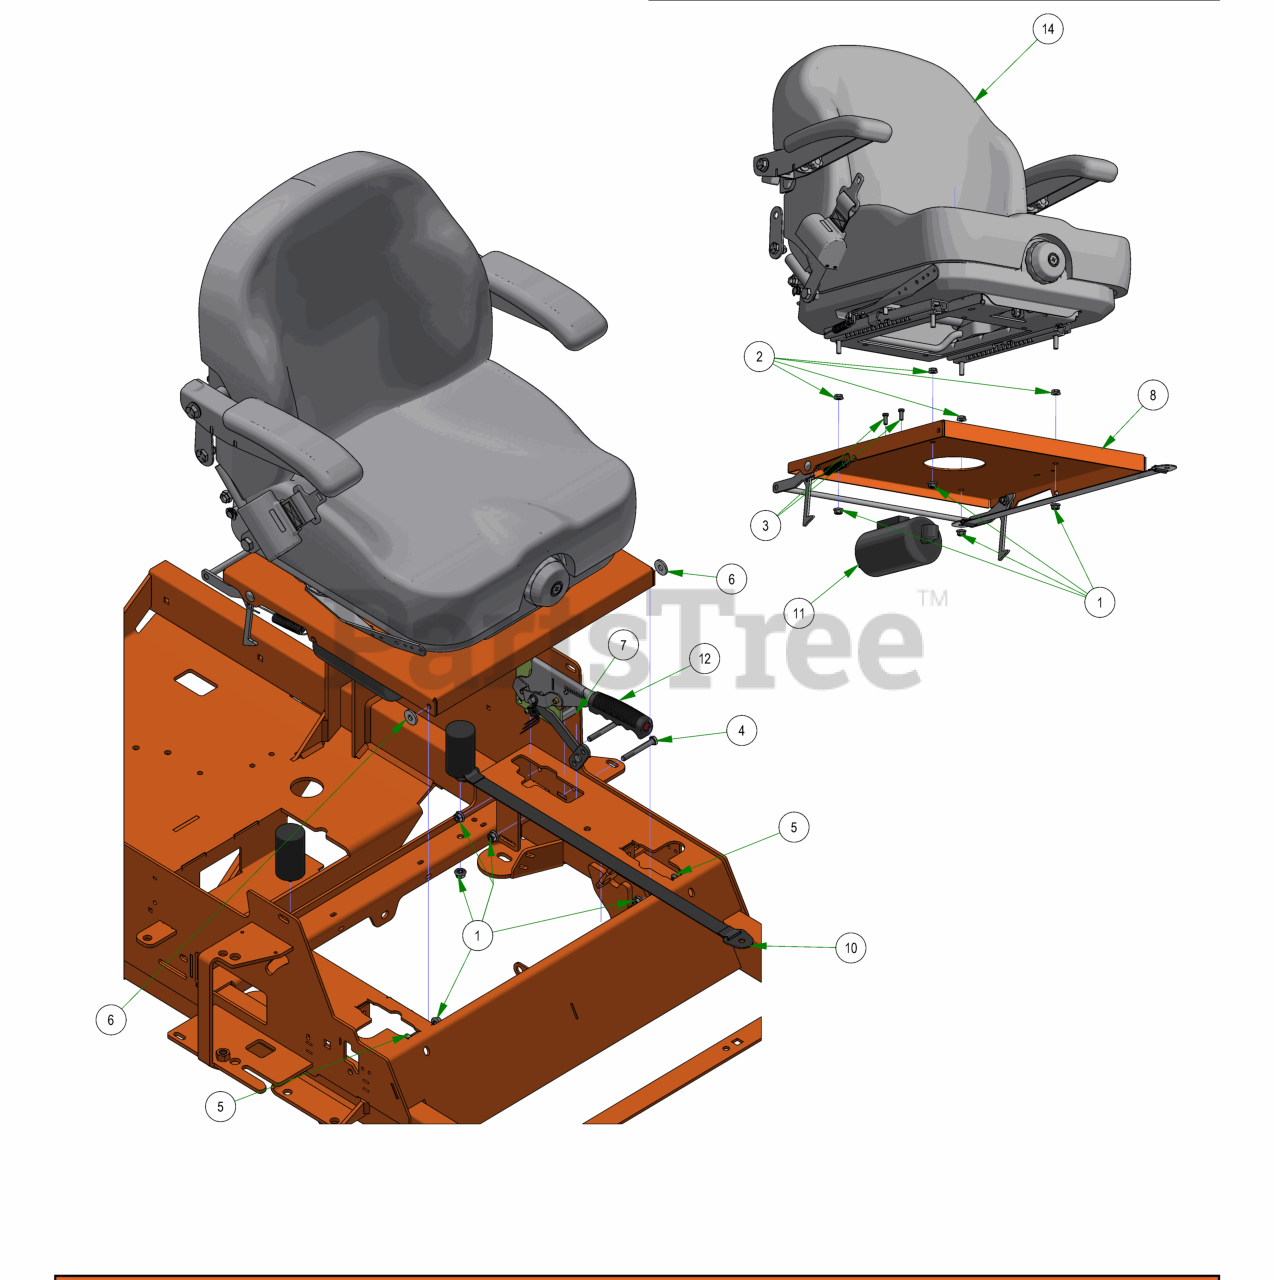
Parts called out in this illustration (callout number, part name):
1	5/16-18 NYLON INSERT FLANGE LOCKNUT ZINC
2	5/16-18 HEX SERRATED FLANGE NUT HARD/ZINC
3	M6-1.0 X 16MM DIN 933 HEX TAP BOLT (CL 8.8) ZINC
4	5/16-18 X 2-1/2 HEX CAP SCREW (GR.5) ZINC
5	5/16-18 X 1 CARRIAGE BOLT (GR.8) ZINC
6	.360 ID X .983 OD X .120 THICK FLAT WASHER NYLON
7	.380 ID X .625 OD X 1.500 LGTH 2019 OUTLAW BRAKE HANDLE
8	R-SERIES SEAT PLATE ASSEMBLY
9	2019 Bad Boy X Cylindrical Seat Mount
10	Seat Strap with Buckles
11	2019 Outlaw EPA Cannister Assembly
12	2019 Brake Handle Assembly
13	2019 Renegade Gas Frame - Powdercoated
14	2022 Suspension Seat w/Seatbelt
